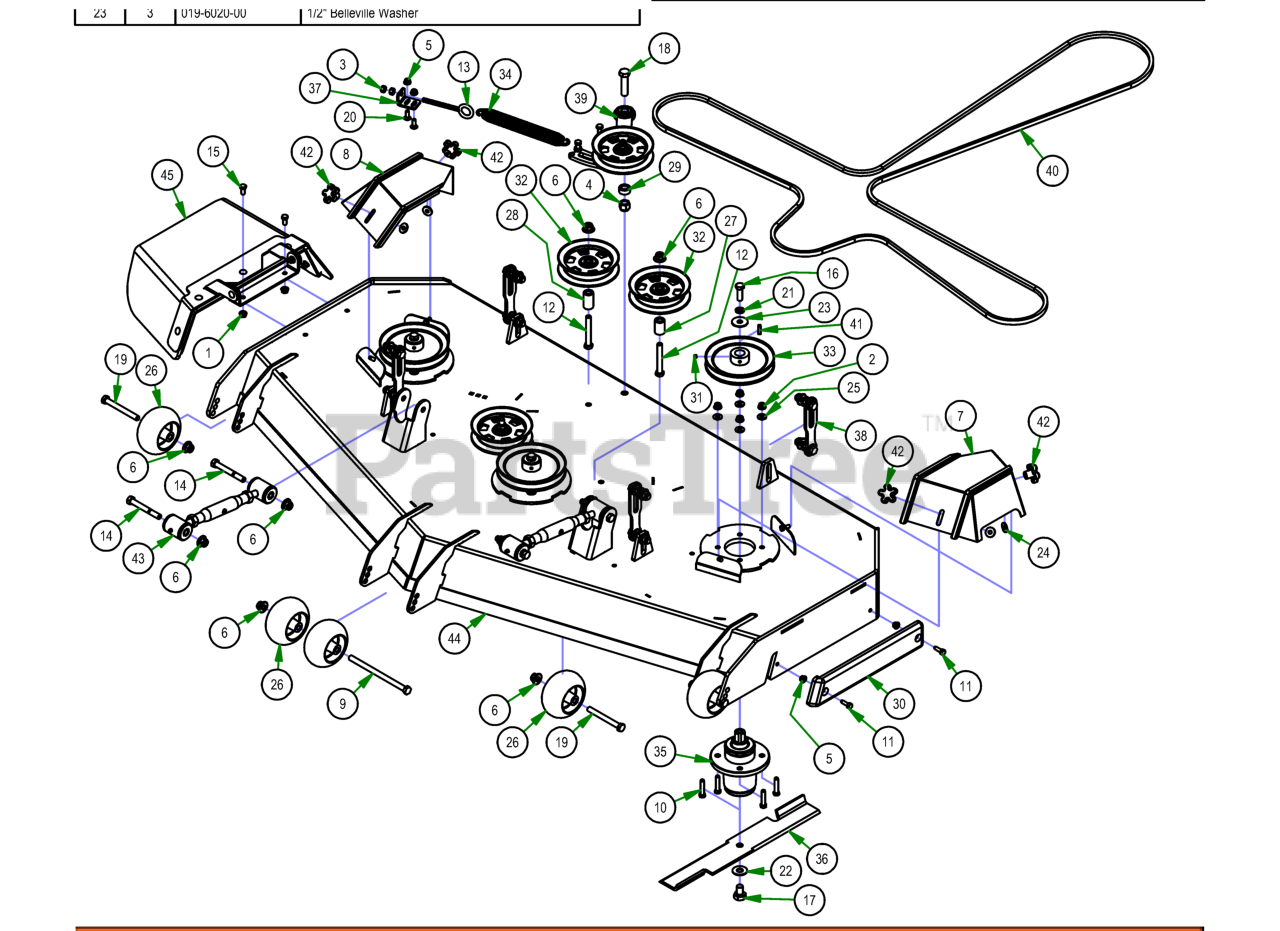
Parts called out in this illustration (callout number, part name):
1	3/8" Flange Nut
2	3/8-16 NYLON INSERT FLANGE LOCKNUT (GR.F) ZINC
3	3/8" Hex Nut
4	5/8 Std NC Nylock Nut
5	5/16" Nylon Flange Nut
6	1/2-13 NYLON INSERT FLANGE LOCKNUT ZINC
7	2019 72" Left Outlaw Gen2 Pulley Cover
8	2019 72" Right Outlaw Gen2 Pulley Cover
9	1/2-13 x 8 Hex Bolt Grade 5
10	3/8-16 X 1-3/4 HEX C/S (GR.5) ZC
11	5/16-18 x 1 GR 5 Hex Bolt Zinc
12	1/2 x 3 1/2 Flange Bolt Grade 8
13	4" 3/8-16 Eye Bolt
14	1/2" x 4" Bolt (Grade 8)
15	3/8" x 3/4" Hex Bolt
16	1/2"-20 x 1 1/2 - Grade 5 Fine Thread Bolt
17	5/8" x 1 1/2" Grade 8 Hex Bolt (Fine)
18	5/8" x 2 1/2" Grade 5 Hex Bolt (Coarse)
19	1/2" x 4 1/2" Bolt
20	5/16" x 7/8" Carriage Bolt
21	1/2" Lock Washer
22	5/8'' Flat Washer
23	1/2" Belleville Washer
24	.360 ID Plastic Washer-Black
25	5/16 USS FLAT WASHER (7/8 OD) ZINC
26	2019 Deck Wheel
27	.502 ID X .750 OD X 1.500 Long Spacer
28	1 3/4" Pulley Spacer
29	5/8" x 1/" Collar W/One Set Screw
30	REVISED TRIM BUMPER_20180226
31	5/16 Set Screw
32	5-3/4 Idler Pulley
33	7" Deck Pulley
34	2019 Outlaw Gen2 Deck Spring
35	OUTLAW SPINDLE ASSEMBLY
36	72" High Lift Fusion Blade
37	2019 Deck Eye Bolt Tab
38	Deck Hangar Assembly
39	2019 Rebel Rogue Deck Idler
40	B202 Belt for 72" Outlaw
41	1/4" x 1" Key
42	5/16" Knob
43	Turnbuckle
44	2019 Sloped 72" Deck
45	2019 Outlaw Gen2 Chute Assembly
